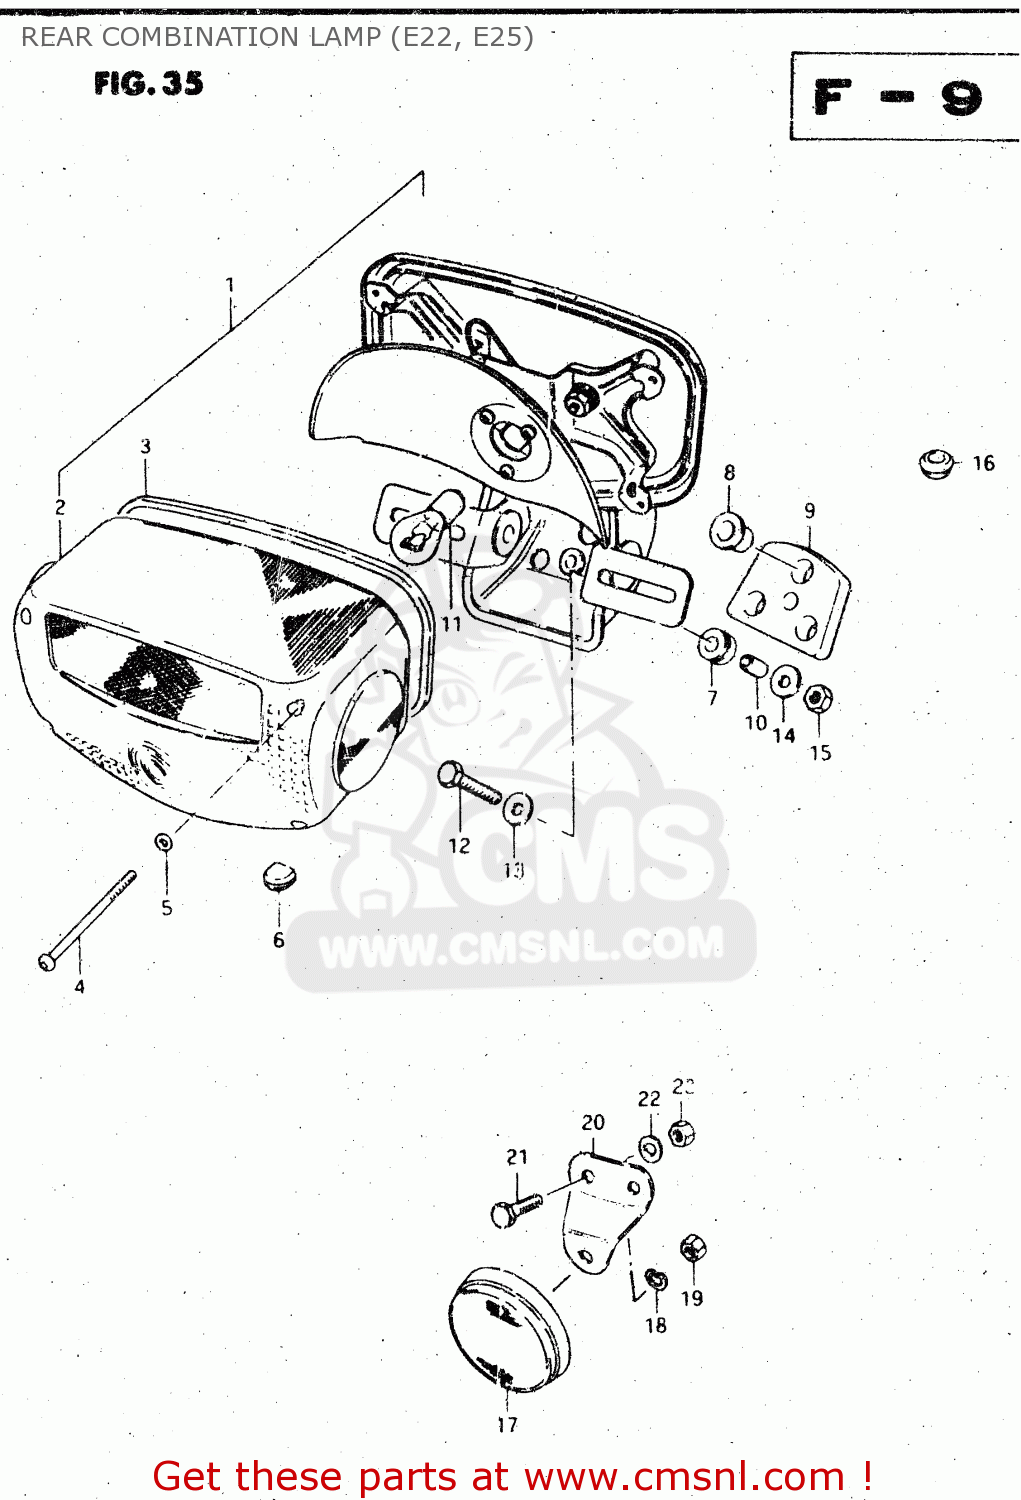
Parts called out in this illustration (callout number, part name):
1	LAMP ASSY,RR C
2	LENS,RR COMBIN
3	GASKET (NAS)
4	SCREW (4X55)
5	GASKET (NAS)
6	GROMMET
7	CUSHION
8	CUSHION
9	CUSHION
10	SPACER
11	BULB(12V21/5W)
12	BOLT
13	WASHER (6.5X20X1.2)
14	WASHER
15	NUT
16	GROMMET
17	REFLEX REFLECTOR,RR
18	LOCK WASHER
19	NUT
20	BRACKET
21	BOLT
22	WASHER
23	NUT
